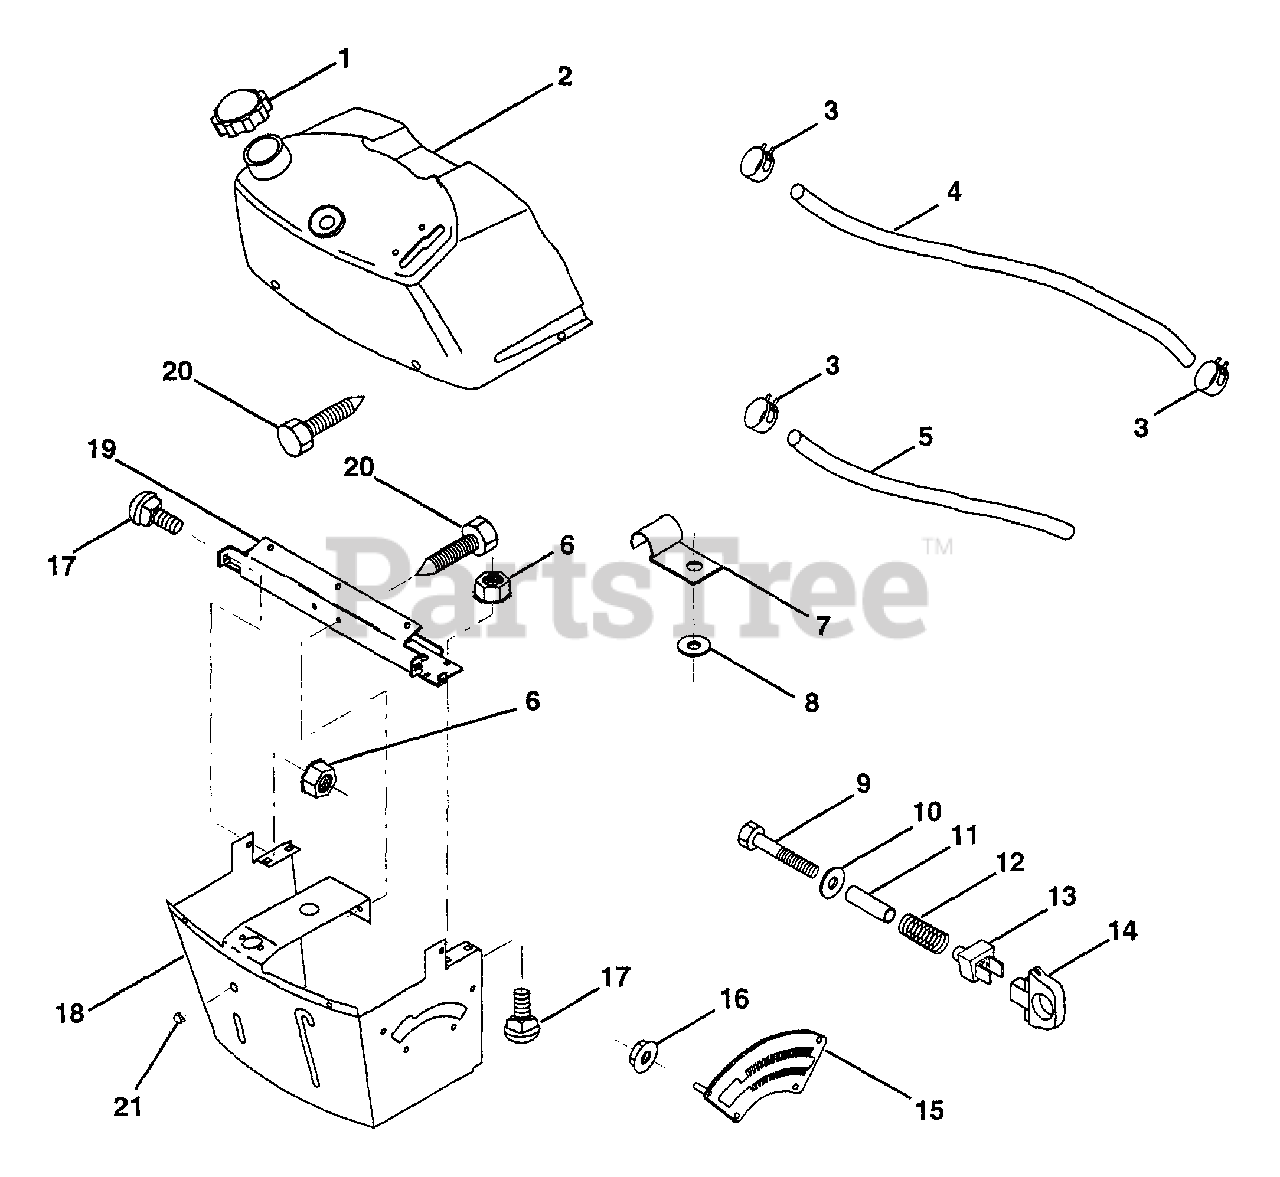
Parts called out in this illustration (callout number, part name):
1	Cap, Fuel
2	Assembly, Dash & Fuel Tank
3	Clamp, Hose
4	Line, Fuel
5	Line, Fuel
6	Nut, Hex, Keps 1/4-20
7	Clip, Fuel Line
8	Washer 9/32 x 3/4 x 16 Gauge
9	Bolt, Hex, Fin. 1/4-20 x 1-3/4
10	Washer 11/32 x 11/16 x 16 Ga.
11	Spacer, Split
13	Clip, Height Adjustment
14	Knob, Height Stop
15	Adjustment, Quadrant Height
16	Nut, Self-Threading 3/16-18
17	Bolt, Carriage 1/4-20 x 1/2 Gr. 5
18	Support Assembly, Dash
19	Brace, Cross
20	Screw, Self-Tapping 1/4-20 x 1/2
21	Plug, Dome, Black
